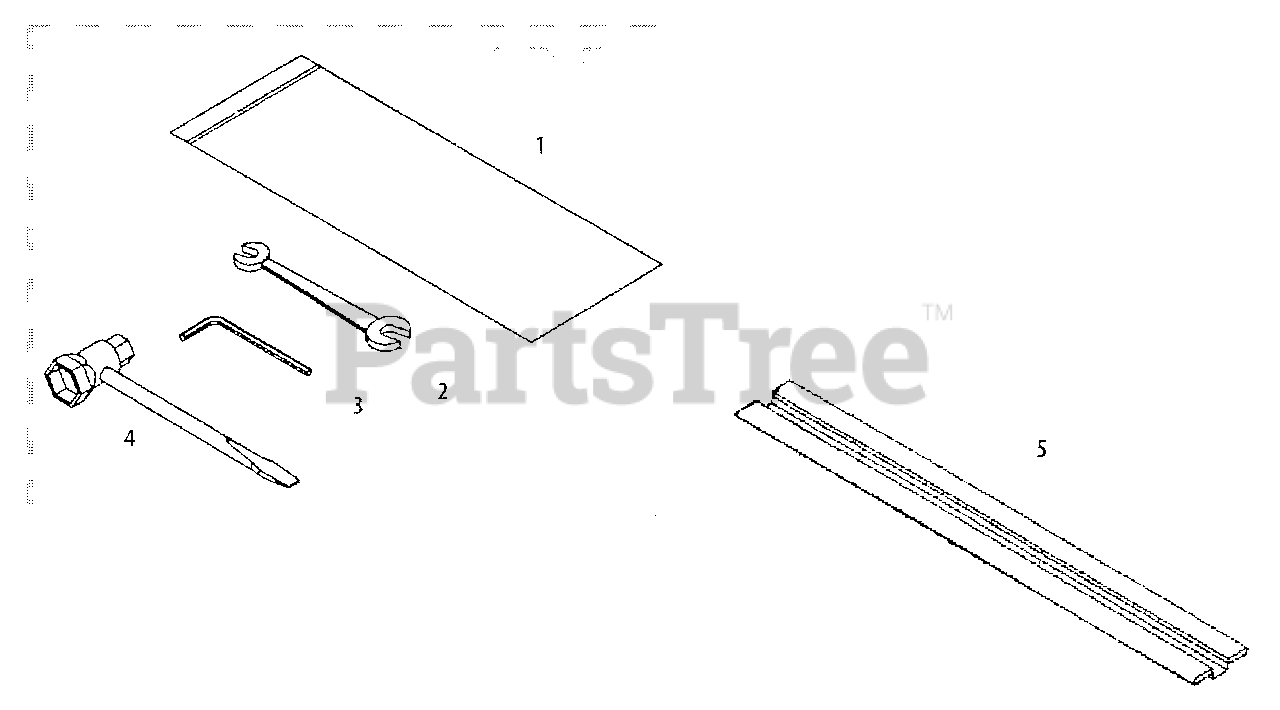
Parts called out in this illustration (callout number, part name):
1	BAG, TOOL
2	SPANNER - 8X10mm
3	HEX KEY - 4mm
4	T-WRENCH
5	COVER, BLADE
65000-92010	TOOL KIT
